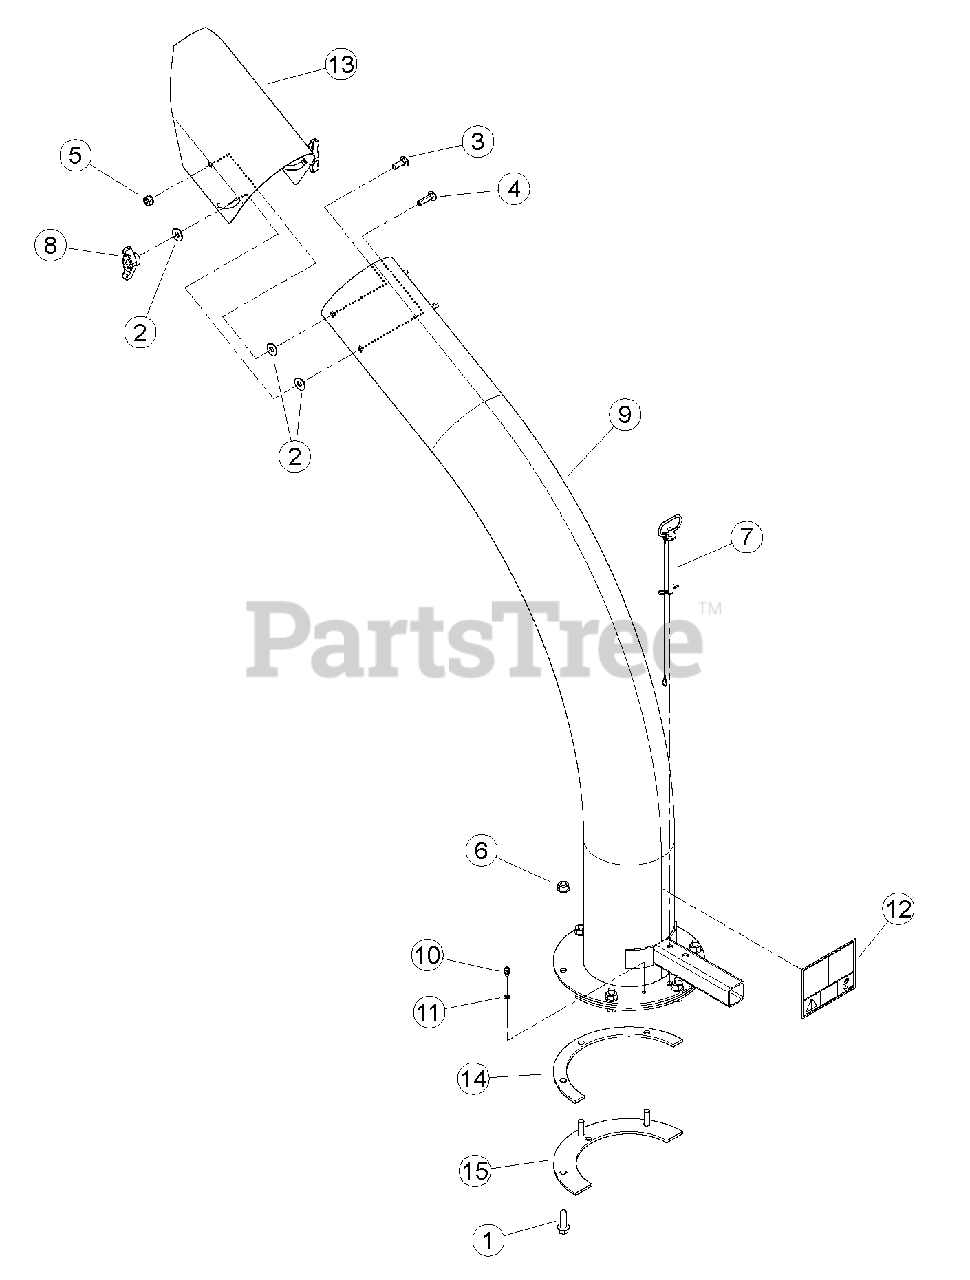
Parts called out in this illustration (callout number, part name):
1	BOLT, 3/8 X 1-1/4 FLANGE NC
2	WASHER, 5/16" FLAT ZP
3	BOLT, 5/16" X 1" GR5 CRG ZP
4	BOLT, 5/16 X 1-1/4" GR5 ZP CRG
5	NUT, 5/16-18 NYLOCK-FLANGE
6	NUT, 3/8-16 NYLOCK FLANGE
7	PIN, 3/8 X 4.25" DISCHARGE
8	KNOB, 5/16-18 UNC TEE W/LOCKING INSERT
9	ASSEMBLY, 6 INCH DISCHARGE CHUTE
10	FITTING, 1/4 SELF-TAP GREASE
11	WASHER, FLAT .254 X .400 X .048
12	DECAL, DISCHARGE DEBRIS & LOCK
13	DEFLECTOR, BLOWER VAC DISCHARGE
14	SPACER, DISCHARGE PIVOT
15	RING, DISCHARGE CLAMP
